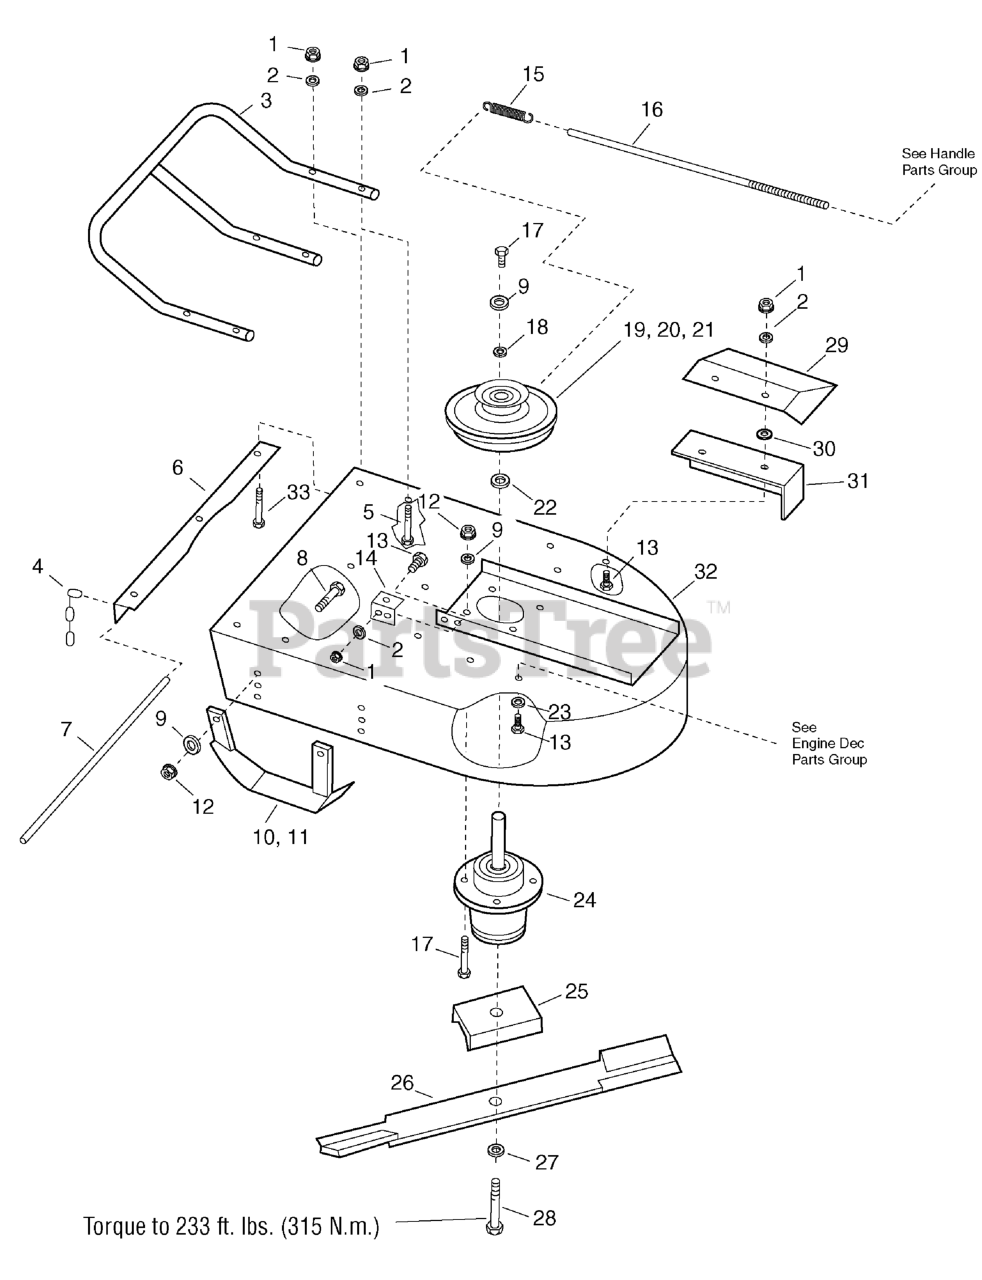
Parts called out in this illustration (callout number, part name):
1	NUT, Hex, 5/16-18
2	Lockwasher, 5/16
3	Front Bumper Bar
4	Chain Curtain Length
5	BOLT, 5/16-18 x 1-1/2
6	Chain Curtain Bracket
7	Chain Curtain Mounting Rod
8	BOLT, 3/8-16 x 1
9	Lockwasher, 3/8
10	Blade Deck Skid - Left
12	NUT, Hex, 3/8-16
13	BOLT, 5/16-18 x 3/4
14	Anti-torque Bracket
15	Clutch Spring
16	Blade Clutch Engagement Rod
17	BOLT, 3/8-16 x 1-1/2
18	Flatwasher, Heavy Duty, 7/16 x 1-1/2
19	Clutch Assembly
22	Clutch Spacer - 1/4
23	Flatwasher, 3/8
24	Blade SpindleAssembly
25	Cutting Blade Reinforcement Channel
26	Cutting Blade
27	Lockwasher, 5/8
28	CAPSCREW, Socket Head, 5/8-11 x 1-1/2
29	Discharge Deflector
30	Flatwasher, 5/16
31	Discharge Cover
32	Blade Deck
33	BOLT, 5/16-18 x 1-3/4
